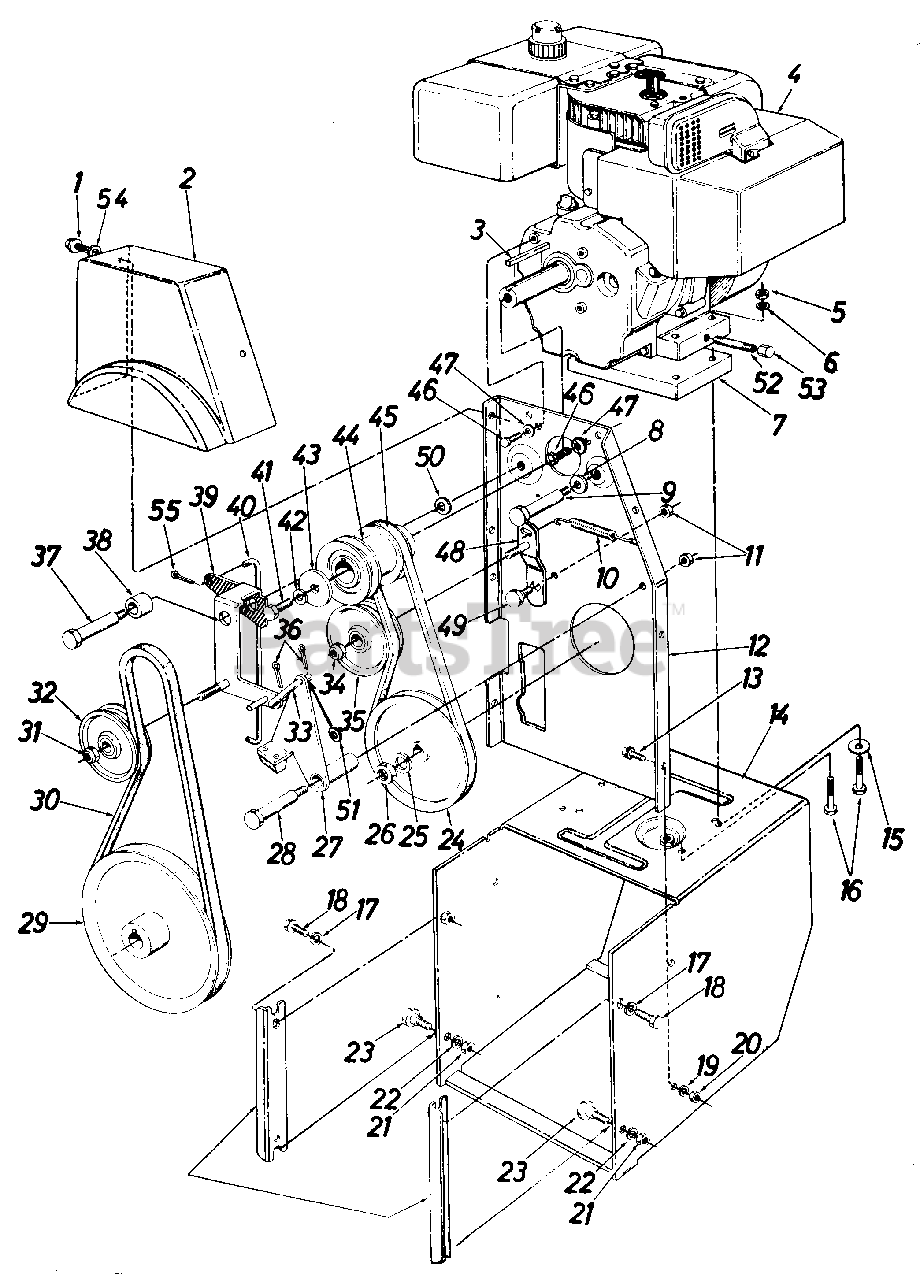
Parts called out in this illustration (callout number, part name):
1	Hex AB-Tap Scr. 5/16 x .75" Lg.
2	Belt Cover
3	Sq. Key 1/4" X 1.50" Lg.
4	Engine
5	Hex Nut 5/16-18 Thd.
6	L-Wash. 5/16" I.D.
7	Engine Spacer Ass'y.
8	Bell-Wash. .40 I.D. x .88 O.D.
9	Shld. Bolt .498" Dia. x 3.00" Lg.
10	Ext. Spring .38 O.D. x 3.18" Lg.
11	Hex Cent. L-Nut 3/8-16 Thd.
12	Engine Brkt. Ass'y.
13	Hex Sems Scr. 5/16-18 x .75" Lg.
14	Frame Ass'y.
15	Fl-Wash. .345 I.D. x .75 O.D. x .060
16	Hex Bolt 5/16-18 x 2.50" Lg.
17	L-Wash. 3/8" I.D. H.D.
18	Pilot Scr. 3/8-16 x .88" Lg.
19	L-Wash. 5/16a I.D.
20	Hex Nut 5/16-18 Thd.
21	Hex Nut 3/8-16 Thd.
22	L-Wash. 3/8" I.D. H.D.
23	Shld. Bolt .498" Dia. x .340" Lg.
24	V-Puiley .628 I.D. x 7.50 O.D.
25	L-Wash. for 5/8" I.D.
26	Hex Ins. Jam L-Nut 5/8-18 Thd.
27	Brake Brkt. Ass'y.
28	Shld. Bolt .498" Dia. x 2.00" Lg.
29	V-Pulley .875 I.D. x 10.12 O.D.
30	"V"-Belt
31	Hex Ins. Jam L-Nut 3/8-24 Thd.
32	Fl-Idler w/Flanges 3.0 O.D.
33	Brake Linkage Ass'y.
34	Hex Ins. Jam L-Nut 3/8-24 Thd.
35	3.0" O.D. Fl-Idler w/Flanges
36	Int. Cot. Pin 3/32" Dia.
37	Shld. Bolt .625" Dia. x 2.750" Lg.
38	Spacer .75 O.D. x 1.00" Lg.
41	Hex Bolt 3/8-24 x 1.25" Lg.
42	L-Wash. 818" I.D. H.D.
43	Fl-Wash.
44	Engine Pulley Double Groove
45	"V"-Belt
46	Hex Bolt 5/16-24 x .62" Lg.
47	Bell-Wash. .345 I.D. x .88 O.D. x .060
48	Drive Idler Brkt. Ass'y.
49	Shld. Bolt .625" Dia. x 1.70" Lg
50	Bell-Wash. .40 I.D. x 1.12 O.D.
51	Fl-Wash. 885" I.D. x .620" O.D.
52	Pipe Nipple 1/4" Pipe Thd. x 3.5" Lg.
53	Hex Hd. Cap 1/4-18 Pipe Thd.
54	Fl-Wash. .340 I.D. x .62 O.D. x .62
55	Int. Cot. Pin 5/16" Dia.
